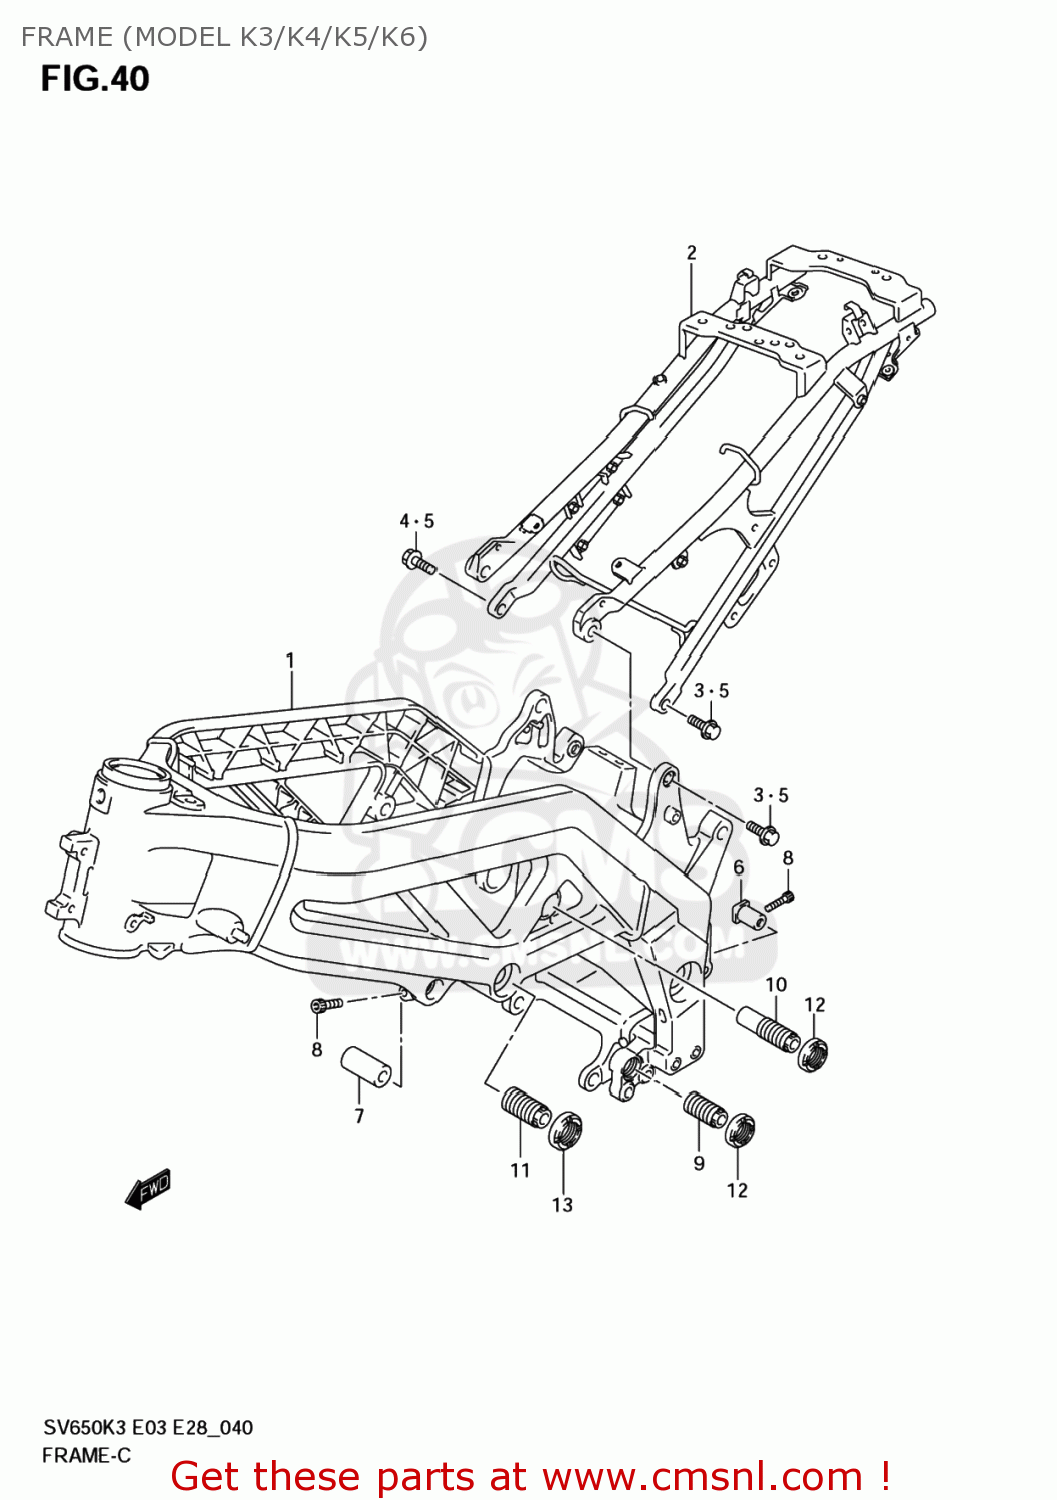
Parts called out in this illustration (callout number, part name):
1	FRAME(SILVER)
2	RAIL,SEAT
3	BOLT(10X30)
4	BOLT, SEAT LOWER RH
5	BOLT,SEAT RAIL
6	SPACER,MOUNTING RR UPR,R
7	SPACER,ENG HEAD MTG RR,L
8	BOLT
9	BOLT,CASE LWR & RR HEAD ADJ
10	BOLT,ENGINE MOUNTING RR,L
11	BOLT,CRANK CASE ADJUST CTR
12	NUT,CRANK CASE ADJUST BOLT
13	NUT,CRANKCASE ADJUST
